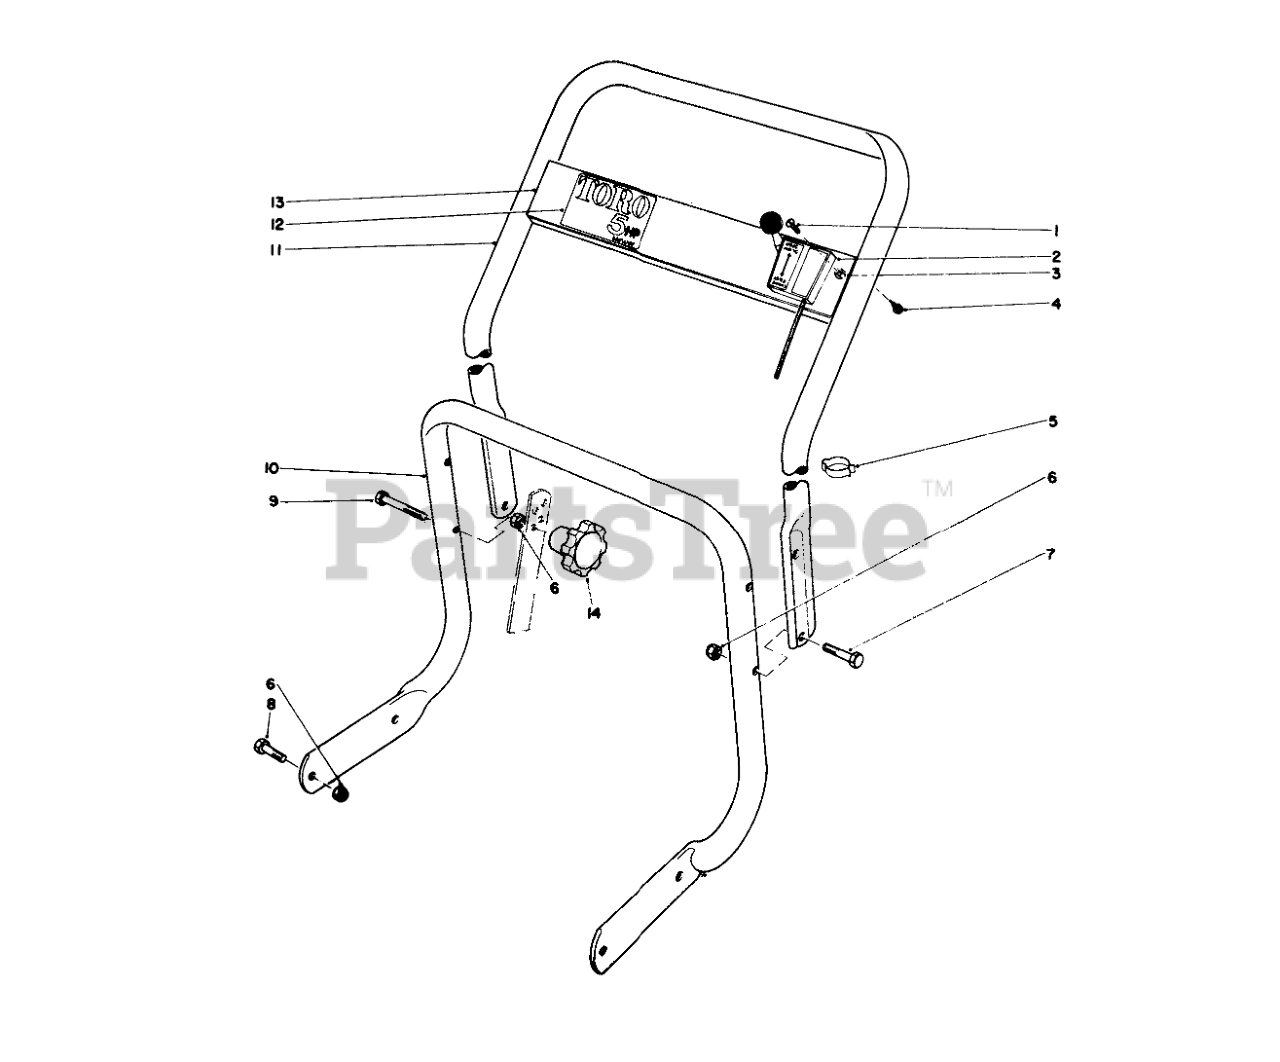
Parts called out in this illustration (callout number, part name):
1	8-32 X 1/2 RND HD MS
2	Throttle Control
3	NUT-HEX
4	SCREW-HWHTF
6	NUT-LOCK, CONE
7	SCREW-HH
8	SCREW-HH
9	SCREW-HH
10	HANDLE
11	UPPER HANDLE
12	ESCUT PLATE DECAL
13	BLOWER ESCUTCHEON PLT
